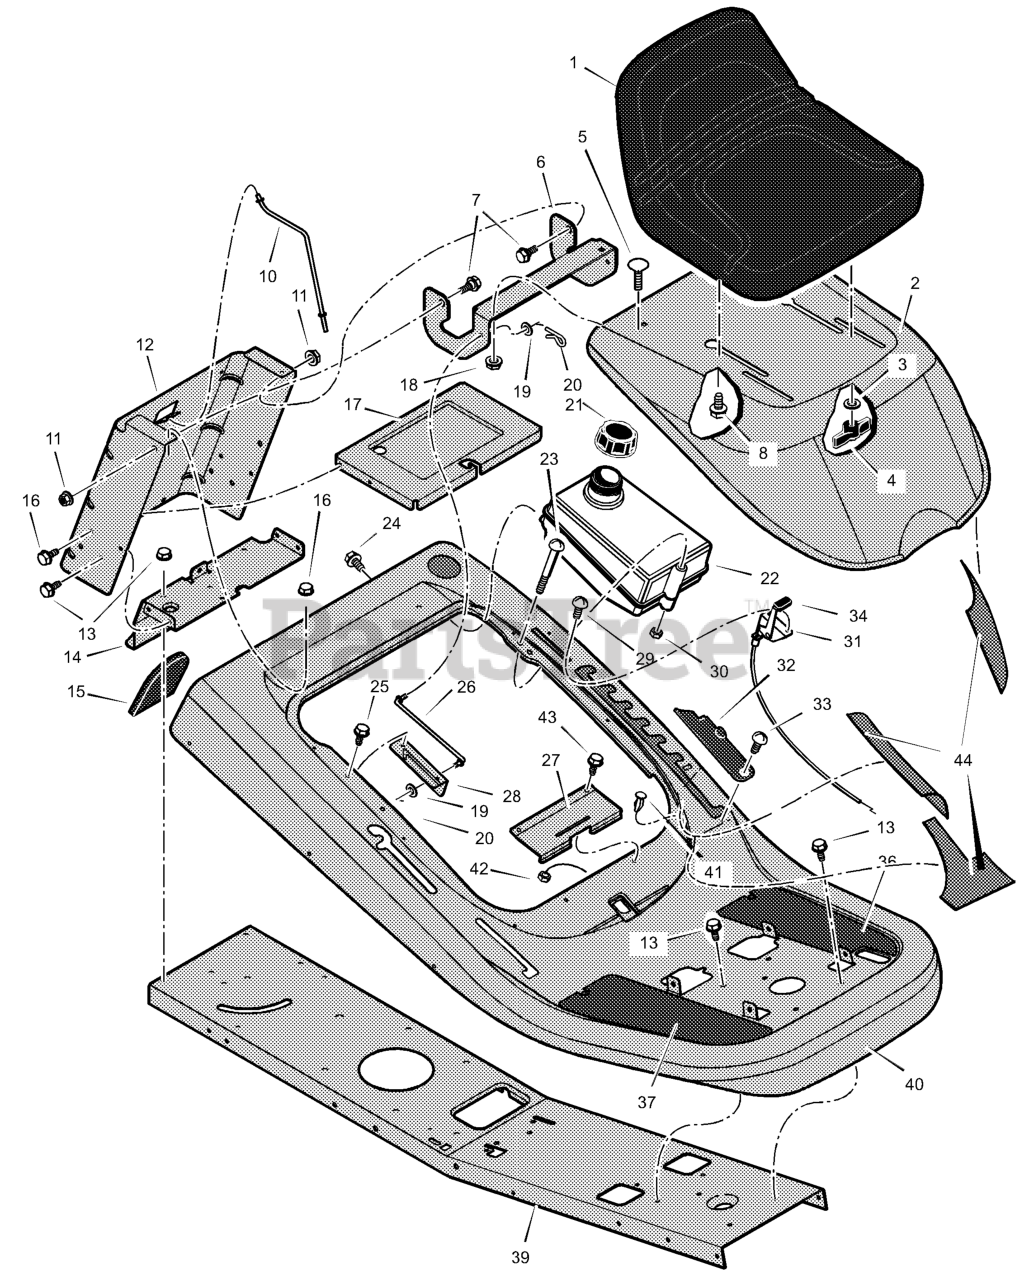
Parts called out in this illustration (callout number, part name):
1	Seat
3	Washer
4	Bolt, Wing
5	Bolt, Carriage
6	Bracket, Hinge
7	Bolt, Shoulder
8	Bolt, Shoulder
10	Rod, Battery
11	Nut, Flange
12	Plate, Rear
14	Plate, Hitch
17	TRAY, Battery
18	Nut, Flange
19	Washer
20	Pin, Cotter
21	Cap, Fuel Tank
22	Tank, Fuel
23	Screw
26	Rod, Hood Prop
27	Spring, Seat Deck
28	Bracket, Prop Rod
30	Nut, NY-Lock
31	Control, Throttle
32	Cover, Detent (Black)
33	Bolt, Shoulder
36	Footmat, Left (Black)
37	Footmat, Right (Black)
40	Deck, Seat
41	Bumper
42	Nut
43	Screw
44	Kit, Foil Heat Shield
